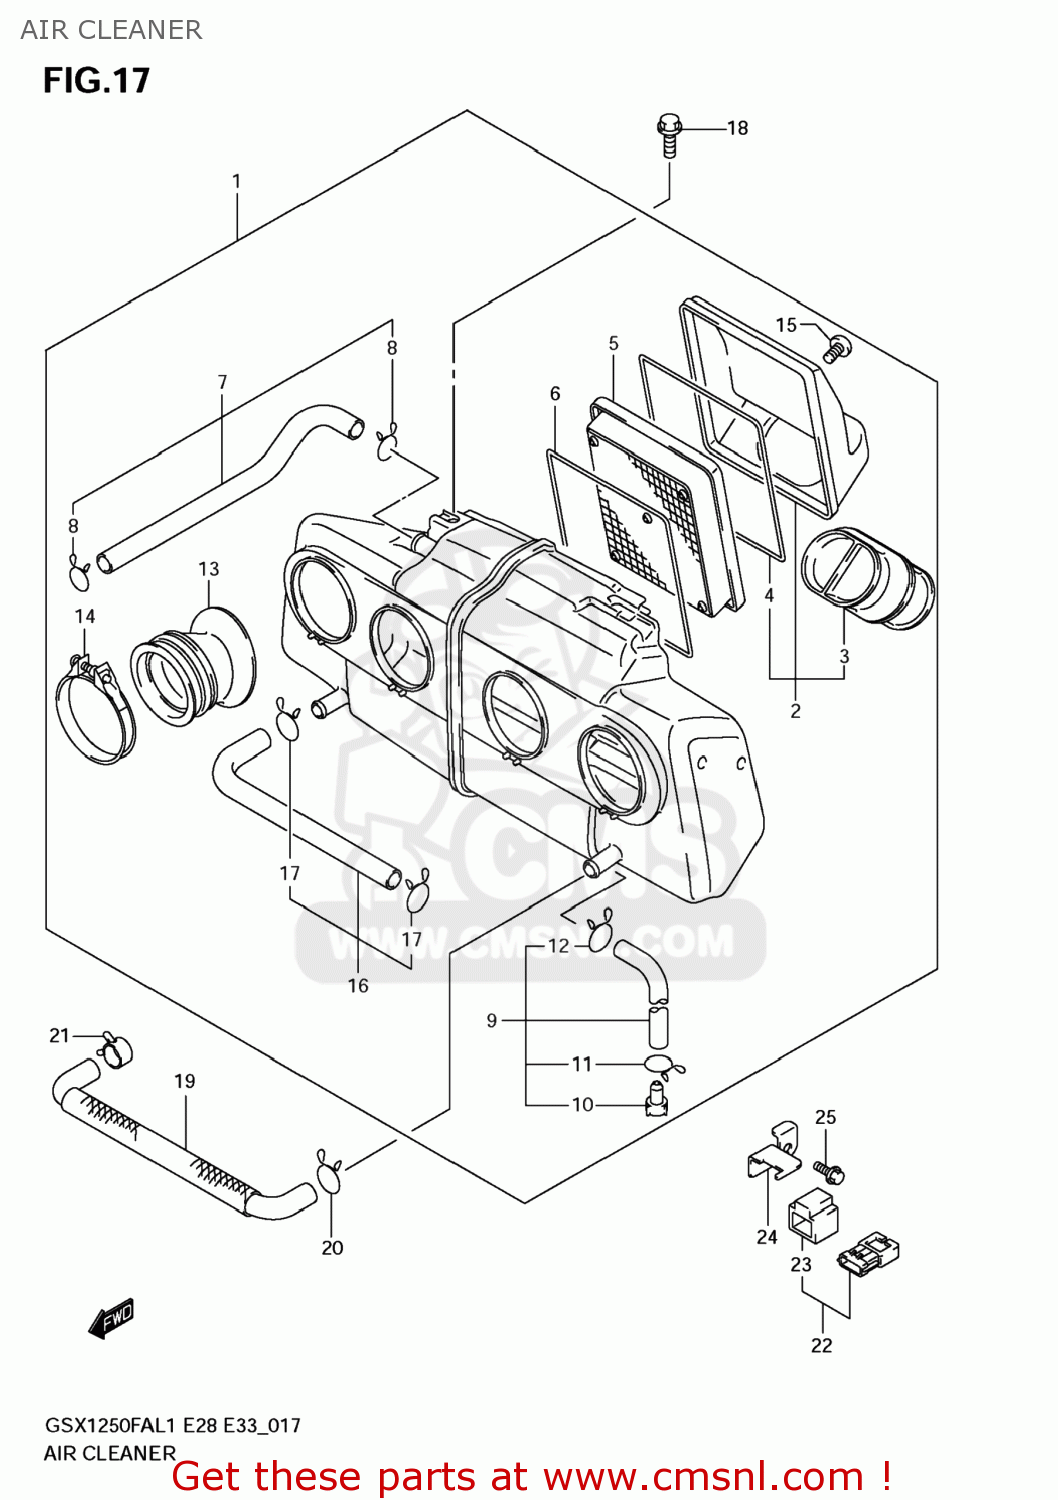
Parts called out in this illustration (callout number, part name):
1	CLEANER ASSY,A
2	CAP,AIR CLEANER
3	TUBE,INLET
4	GASKET (NAS)
5	FILTER ASSY
6	GASKET (NAS)
7	TUBE,BREATHER
8	CLIP
9	TUBE,DRAIN
10	PLUG
11	CLIP
12	CLIP
13	TUBE,OUTLET
14	CLAMP,OUTLET TUBE
15	SCREW
16	TUBE
17	CLIP
18	BOLT
19	HOSE,ISC VALVE
20	CLIP
21	CLIP
22	SENSOR,BOOST
23	COVER
24	BRACKET,BOOST SENSOR
25	BOLT
